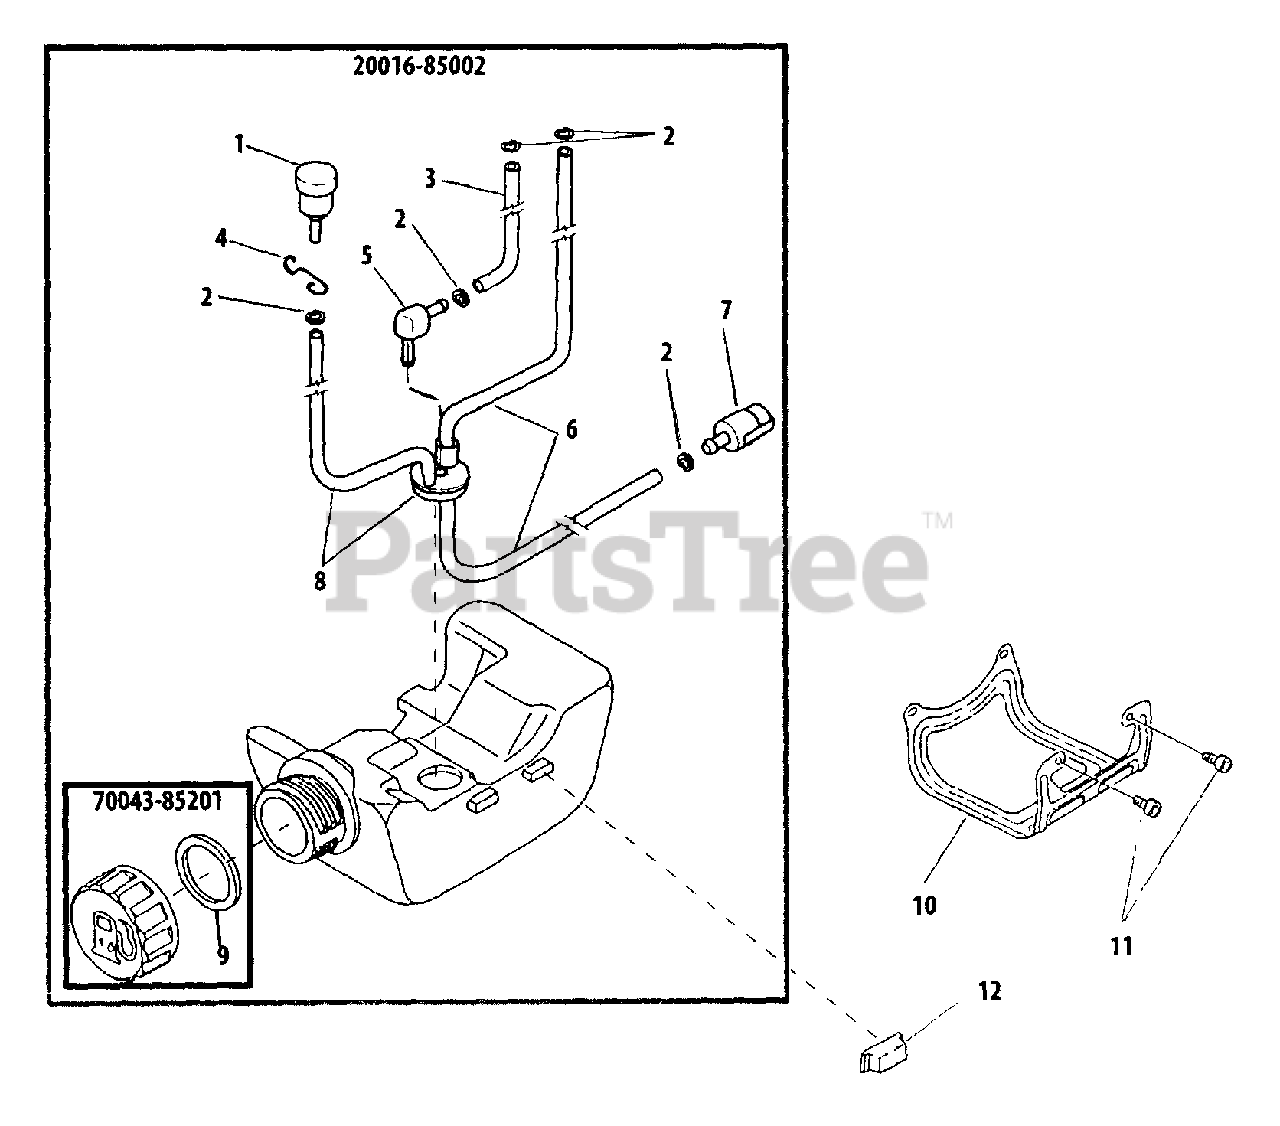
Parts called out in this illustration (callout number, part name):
1	VENT ASSY
2	CLIP Ø6
3	PIPE, RETURN
4	CLIP, VENT ASSY
5	CONNECTOR, PIPE
6	PIPE, FUEL
7	FILTER, FUEL 125-528
8	GROMMET
9	GASKET, FUEL CAP
10	GUARD, METAL FUEL TANK
11	BOLT M5×12
12	CUSHION, FUEL TANK
20016-85002	FUEL TANK ASSY
70043-85201	CAP ASSY, FUEL
